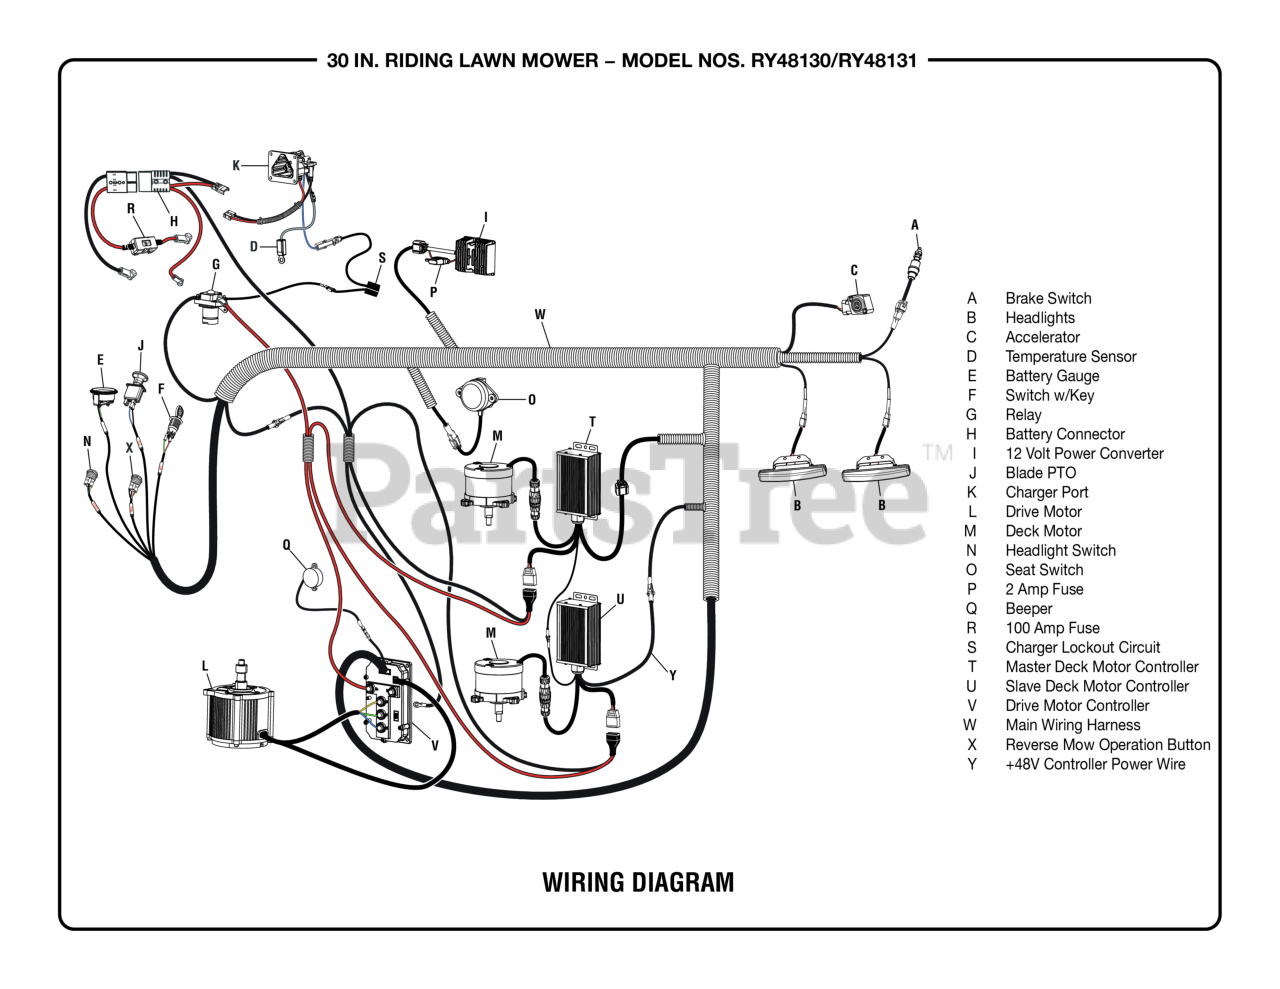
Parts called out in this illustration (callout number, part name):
A	Brake Switch
B	Headlights
C	Accelerator
D	Temperature Sensor
E	Battery Gauge
F	Switch w/Key
G	Relay
H	Battery Connector
I	12 Volt Power Converter
J	Blade PTO
K	Charger Port
L	Drive Motor
M	Deck Motor
N	Headlight Switch
O	Seat Switch
P	2 Amp Fuse
Q	Beeper
R	100 Amp Fuse
S	Charger Lockout Circuit
T	Master Deck Motor Controller
U	Slave Deck Motor Controller
V	Drive Motor Controller
W	Main Wiring Harness
X	Reverse Mow Operation Button
Y	+48V Controller Power Wire
